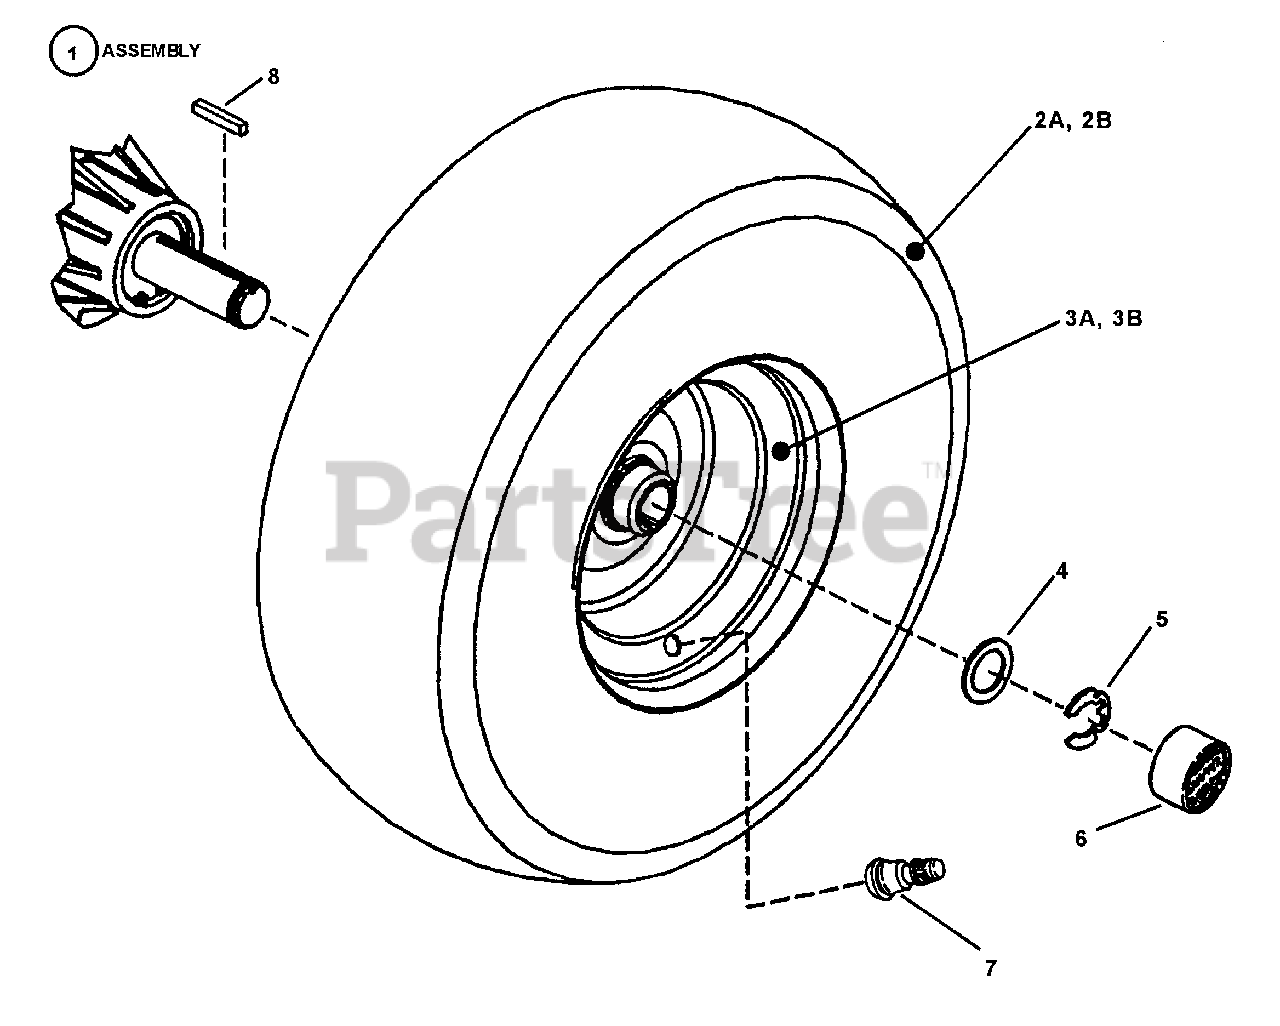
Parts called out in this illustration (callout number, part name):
1	ASSEMBLY, Rear Tire & Rim
2A	TIRE, 18 x 7.00-8, Multi-Trac
2B	TIRE, 18 x 8.50-8, Multi-Trac
3A	RIM, 18 x 6.50
3B	RIM, 18 x 8.50
4	BUSHING, Machine
5	RING, Retaining, External 1"
6	CAP, Hub
7	STEM, Valve
8	KEY, Square M6 x 38mm
